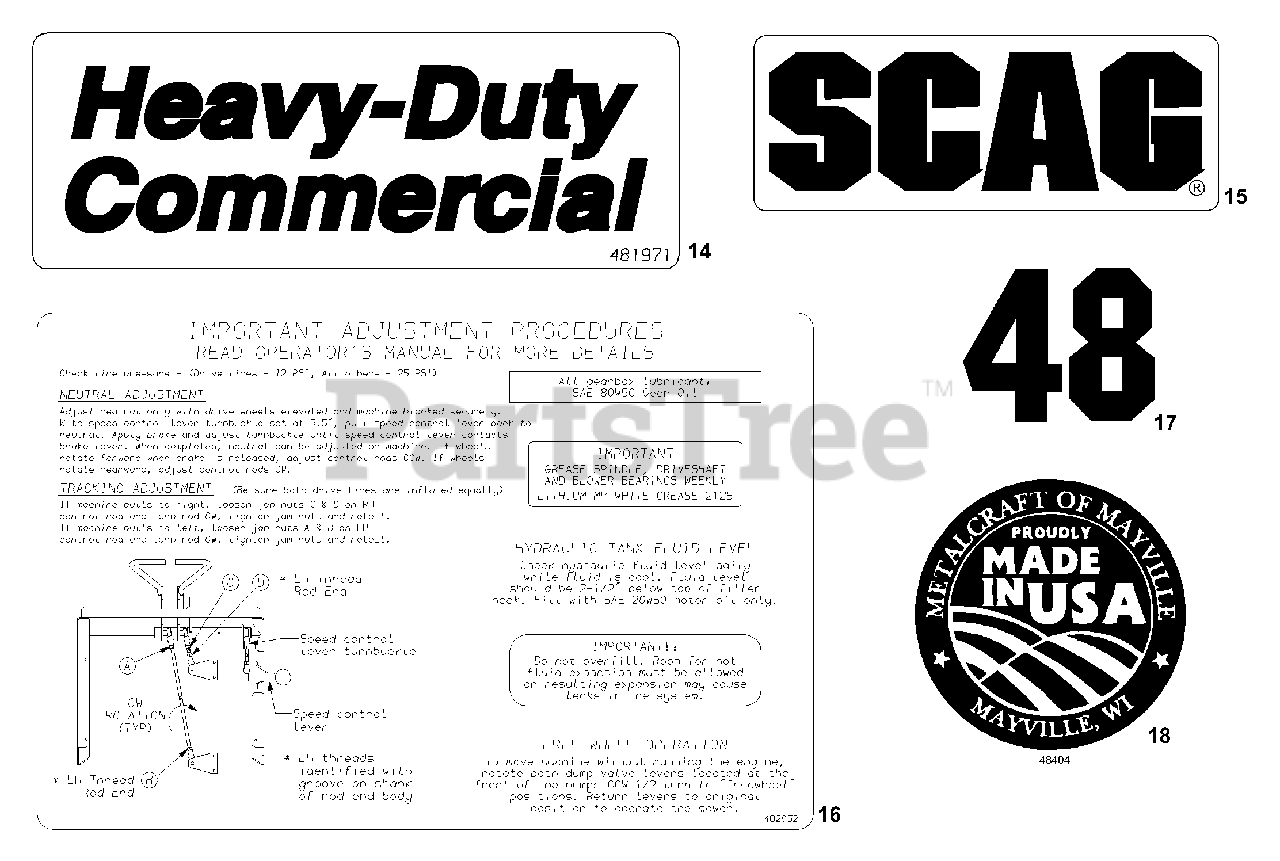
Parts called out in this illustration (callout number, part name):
14	1
15	1
16	1
17	1
18	1
